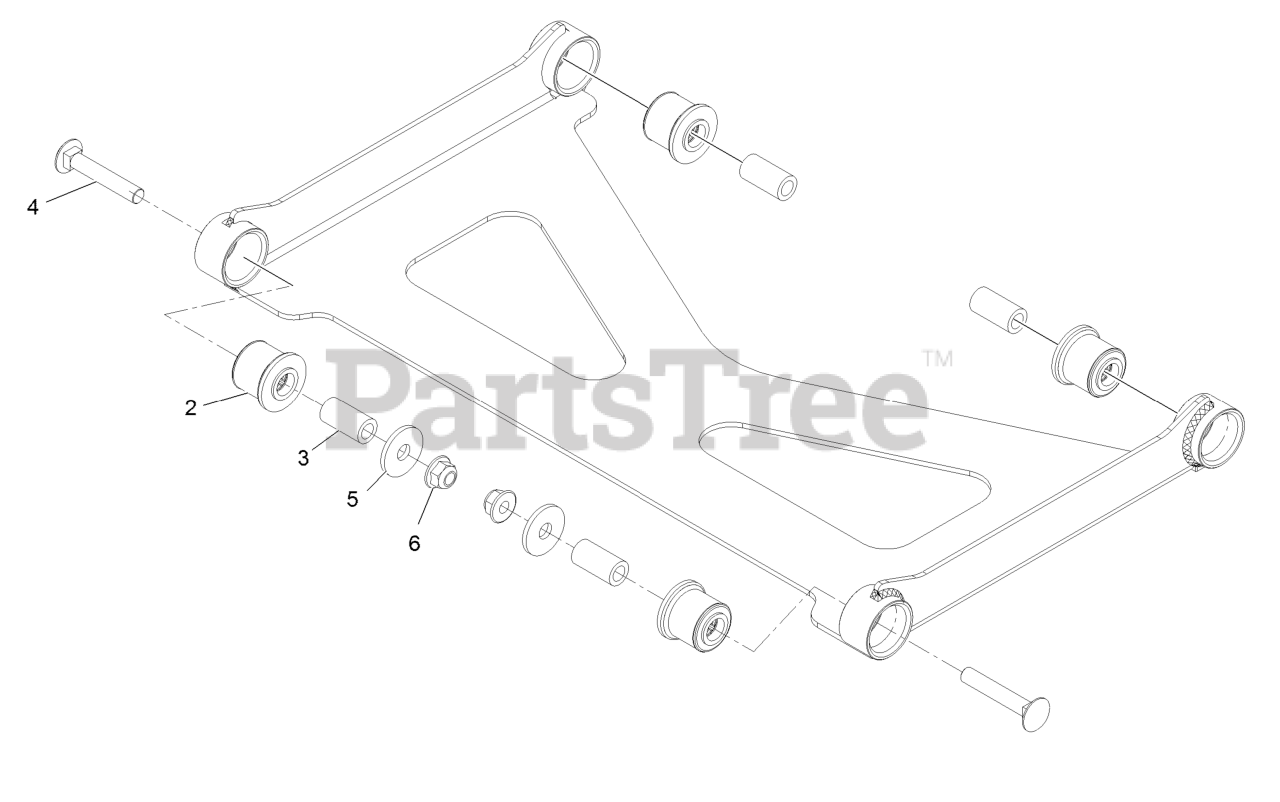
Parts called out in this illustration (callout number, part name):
2	Bushing-Rubber, Suspension
4	Bolt-Carriage 3/8-16 X 2 1/4
5	Washer
6	Nut-Nyloc 3/8-16 Flg
